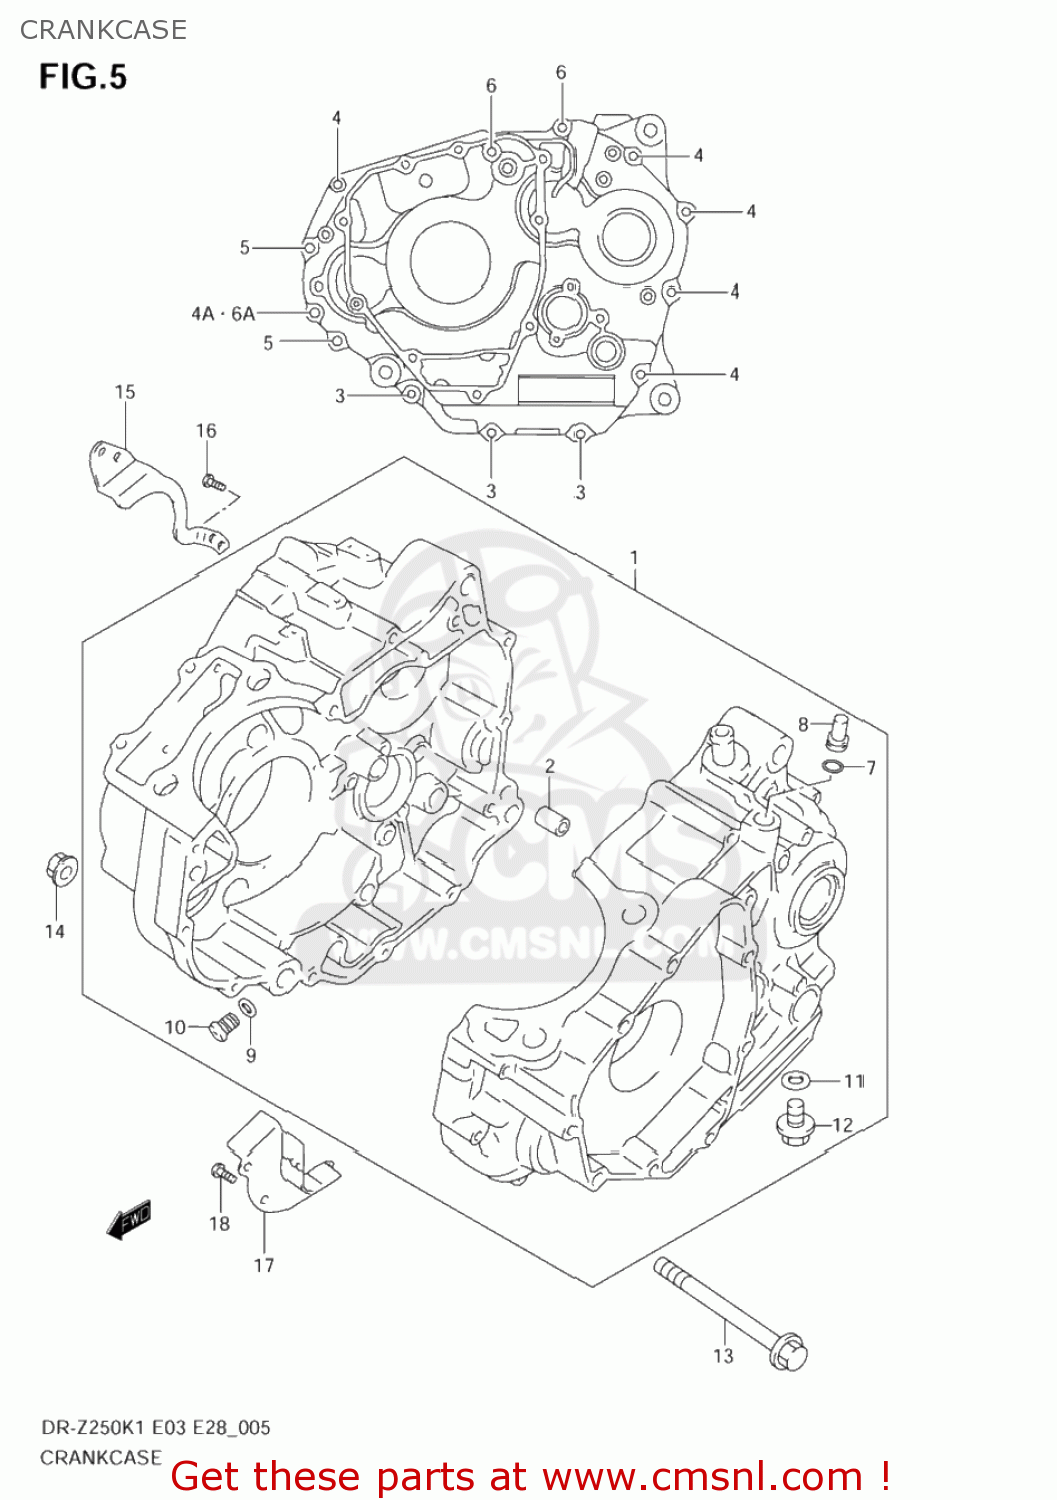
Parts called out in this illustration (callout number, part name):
1	CRANKCASE SET
2	PIN
3	BOLT
4	BOLT
4A	BOLT
5	BOLT
6	BOLT
6A	GASKET(5.8X13X1.2) (NAS)
7	O RING(D:1.2,ID:4)
8	JET(12)
9	GASKET(10X14X3.6) (NAS)
10	PLUG(10X10)
11	GASKET(12.1X16.2X3.7) (NAS)
12	PLUG,12X20
13	BOLT(10X101.5)
14	NUT
15	PLATE,BREATHER OIL RETURN
16	SCREW
17	SEPARATOR,CRANKCASE
18	SCREW(6X12)
